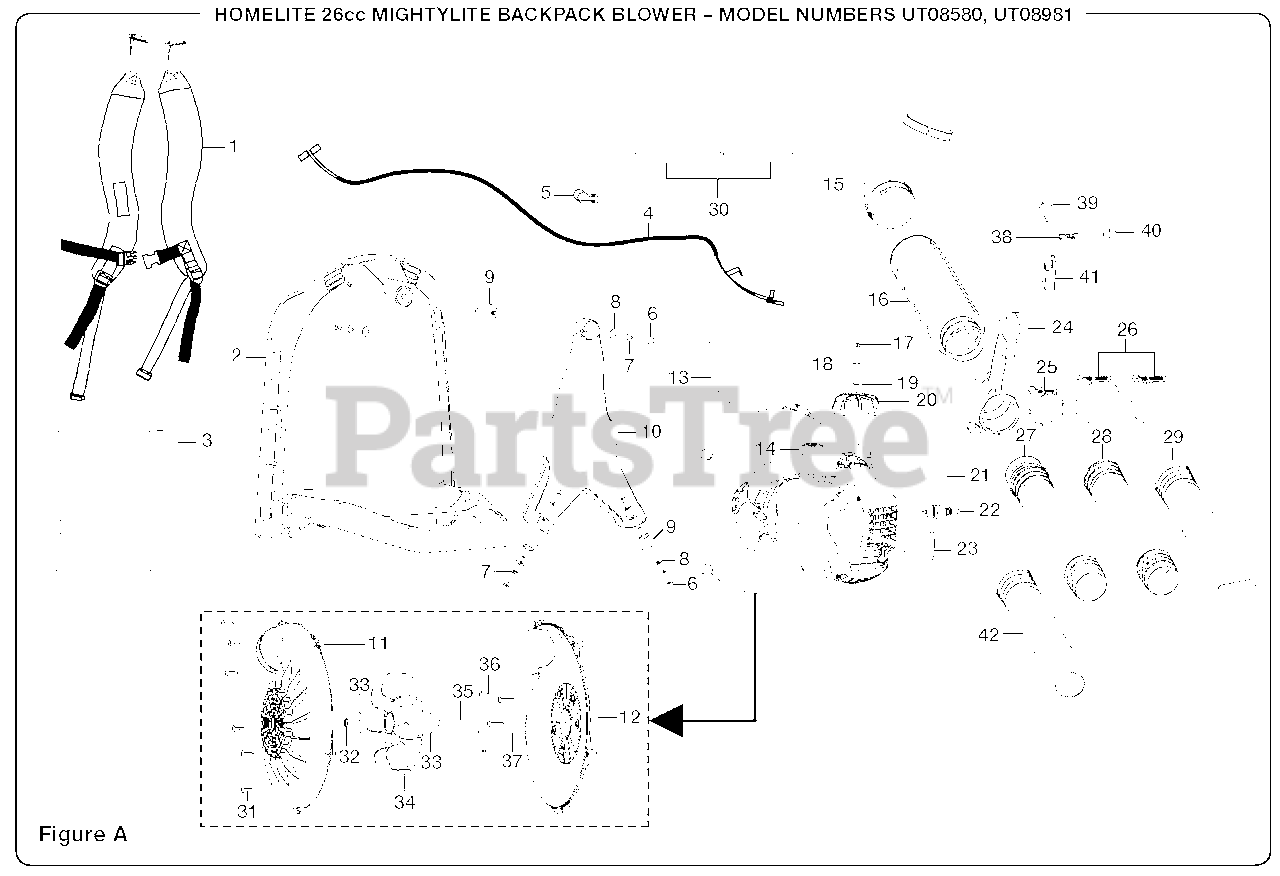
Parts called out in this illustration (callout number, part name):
1	Shoulder Harness Assembly
2	Backpack Frame
3	Mesh Backing
4	Throttle Cable Assembly
5	Cable Clamp
6	Hex Nut (1/4-20)
7	Lock Washer (1/4-20)
8	Washer (1/4-20)
10	Frame Support
11	Bottom Volute
12	Top Volute
13	Starting Label
14	Fuel Cap Assembly
15	Elbow Tube
16	Bellows
17	Hex Nut (M4)
18	Wavy Washer
19	Flat Washer
20	Choke Dial Cover
21	Choke Label
22	Spark Plug (Champion RCJ6Y)
23	Logo Label
24	Throttle Control Handle
25	Small Clamp
26	Large Clamp
27	Upper Tube
28	Lower Tube
29	Wide Sweeper Nozzle
30	Cable Tie
31	Screw (10-14 x 3/4 in.)
32	Lock Nut (3/8-24)
33	Flat Washer
35	Crankshaft Spacer
36	Screw (10-14 x 26.99 mm)
37	Screw (M4 x 77.5 mm)
38	Trigger Lock Spring
39	Switch
40	Throttle Lock
